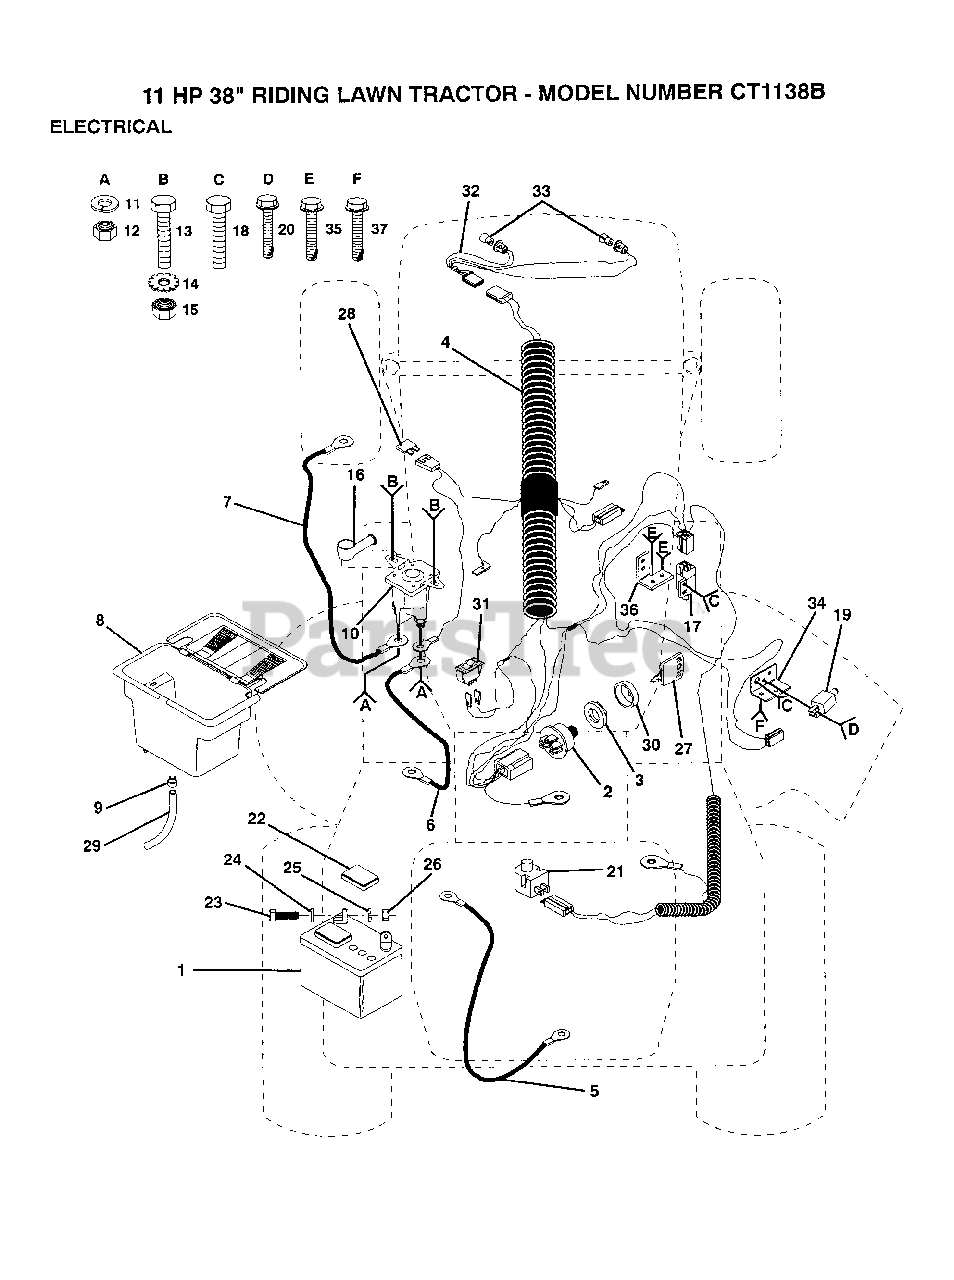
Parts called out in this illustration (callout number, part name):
3	NUT IGNITION
4	IGN HARNESS
5	CABLE T
7	"CABLE T, BATTERY"
9	HOSE CLAMP T
12	NUT
13	BOLT
15	NUT
17	SWITCH INTERLOCKT
18	SCREW
19	SWITCH-INTER. GT
20	SCREW
21	SWITCH SEAT
22	"CAP,BATTERY "
23	BOLT LT
24	WASHER
25	LOCKWASHER
28	FUSE HYT
31	SWITCH LT
32	HARNESS T
34	SWITCH BRACKET
35	SCREW
36	BRACKET LT
37	SCREW
